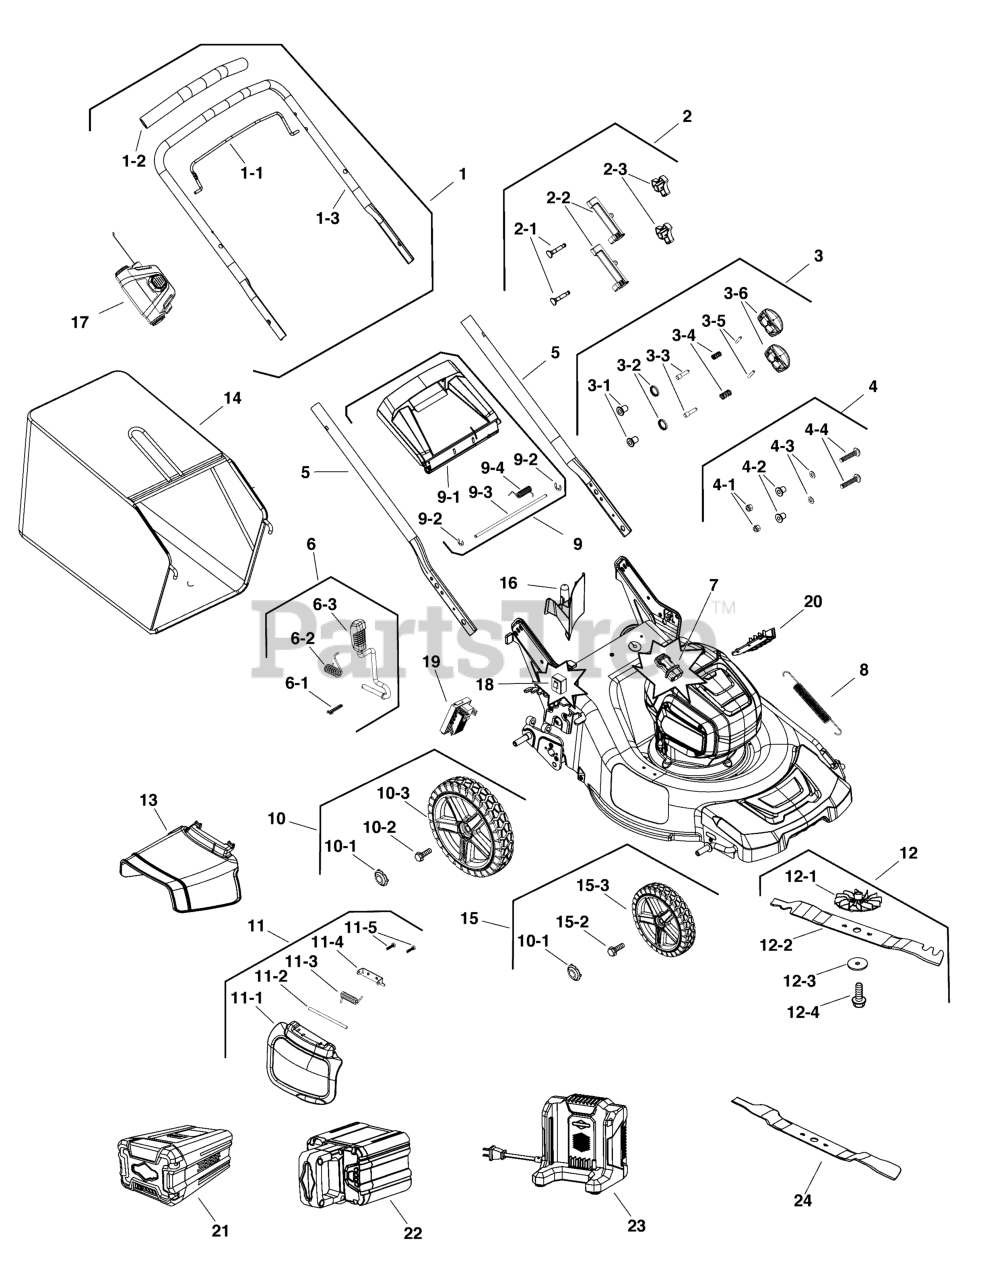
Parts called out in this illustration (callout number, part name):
1	KIT, Upper Handle
1-1	BAIL ASSEMBLY
1-2	GRIP, foam
1-3	HANDLE, Upper
2	KIT, Mounting Hardware
2-1	BOLT
2-2	SLEEVE
3	KIT, Knob, Lower Handle
3-1	INSERT
3-2	GASKET
3-3	POST
3-4	SPRING
3-5	PIN
3-6	KNOB, Handle
4	KIT, Hardware, Lower Handle
4-2	INSERT
4-3	WASHER, Flat
4-4	BOLT
5	KIT, Lower Handle
6	KIT, Height Adjust
6-1	PIN, Cotter
6-2	SPRING
6-3	HANDLE, Height Adjust
7	KEY, Safety
8	SPRING, Tension, Lift
9	KIT, Rear Cover
9-1	COVER, Rear
9-2	WASHER, Split
9-3	ROD, Rear Cover
9-4	SPRING
10	KIT, Rear Wheel, 10"
11	KIT, Cover, Side Discharge
11-1	COVER, Side Discharge
11-2	ROD, Side Discharge
11-3	BRACKET
11-4	BRACKET
12	KIT, Mower Blade, 20"
12-3	WASHER
12-4	BOLT, Flange
13	DEFLECTOR, Side Discharge
14	GRASS CATCHER ASSEMBLY
15	KIT, Front Wheel, 8"
16	PLUG, Mulching
17	CONTROL PANEL ASSEMBLY
18	SWITCH, Safety
19	BOARD, Circuit
20	TERMINAL, Battery
21	* BATTERY, 2.0, 48V
22	* BATTERY, 5.0, 48V
23	* BATTERY CHARGER, 48V
24	MOWER BLADE, Mulching
